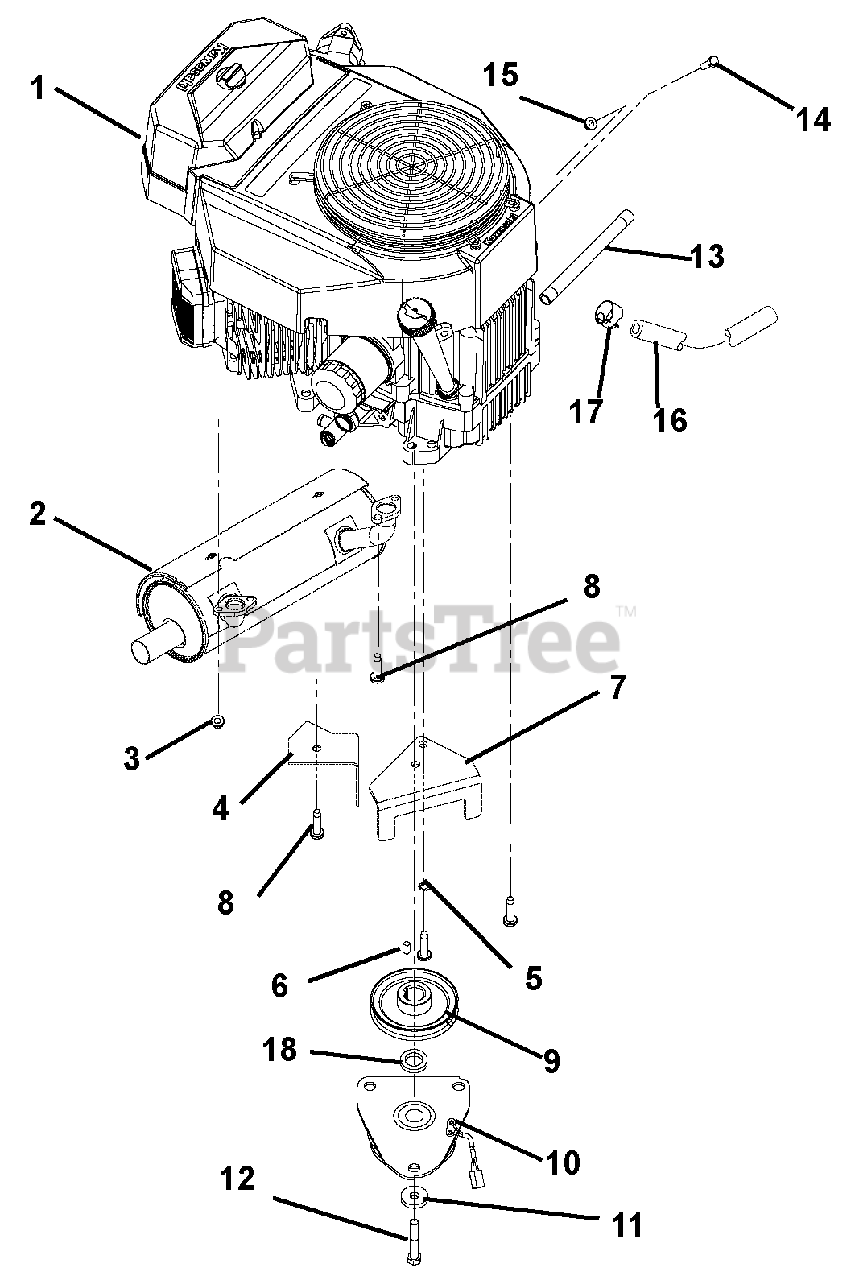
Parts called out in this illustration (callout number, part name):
1	ENGINE, KAWASAKI FR691 (24HP)
2	MUFFLER, KAWASAKI FX 24/26HP
3	NUT-LK-TOP M8-1.25 YWZC
4	GUARD, HD CLUTCH WIRE
5	@WSHR-LK-EXT.391X.628X.036YWZC
6	KEY-SQ .25X.625X.25 SAE 8630
7	ANCHOR - OGURA CLUTCH - HD
8	BLT-HEX.38-16X1.25FTHG5 EP30YZ
9	PULLEY, 4.50 OD X 1.002 ENGINE
10	CLUTCH ASSY, OGURA# GT1A-HU02
11	WSHR-FL-STL .469X2.00X.25 YWZC
12	BLT-HEX .44-20X3.00 G5 YZ EP80
13	HOSE, HYD .38-11-0K M6N0-F6J0
14	@BLT-HEX .31-18X1.00 GR5 YWZC
15	@NUT-LK-NYL-FLG .31-18 YWZC
16	1 INCH OF HOSE, .25 LOW-PERM BULK GAS
17	CLAMP, FUEL LINE
18	SPACER 1.002ID X 1.75 OD X.266
19	@BLT-HEX M8-1.25X20 YWZC
